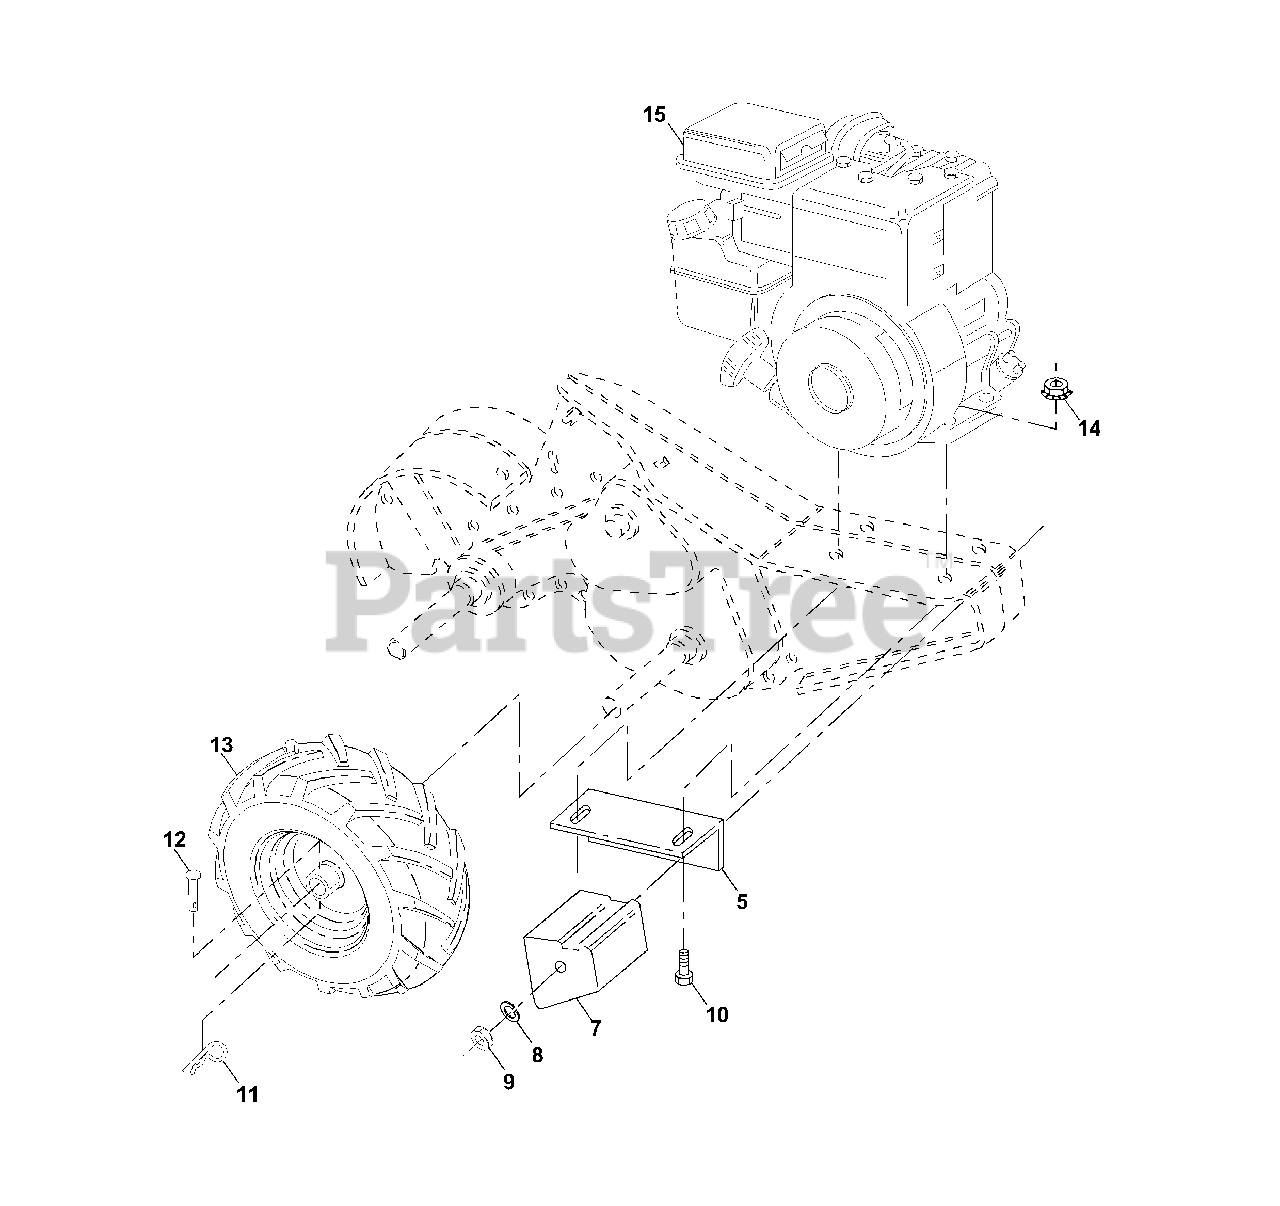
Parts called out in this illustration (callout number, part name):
5	Bracket, Reinforcement
6	Bolt, Hex 5/16-18 x 2
7	Counter Weight, R.H.
8	Washer, Lock 3/8
9	Nut, Hex 3/8-16
11	Clip, Hairpin
12	Rivet, Drilled
13	Tire
13	Tire Valve
14	Nut, Keps 5/16-18
